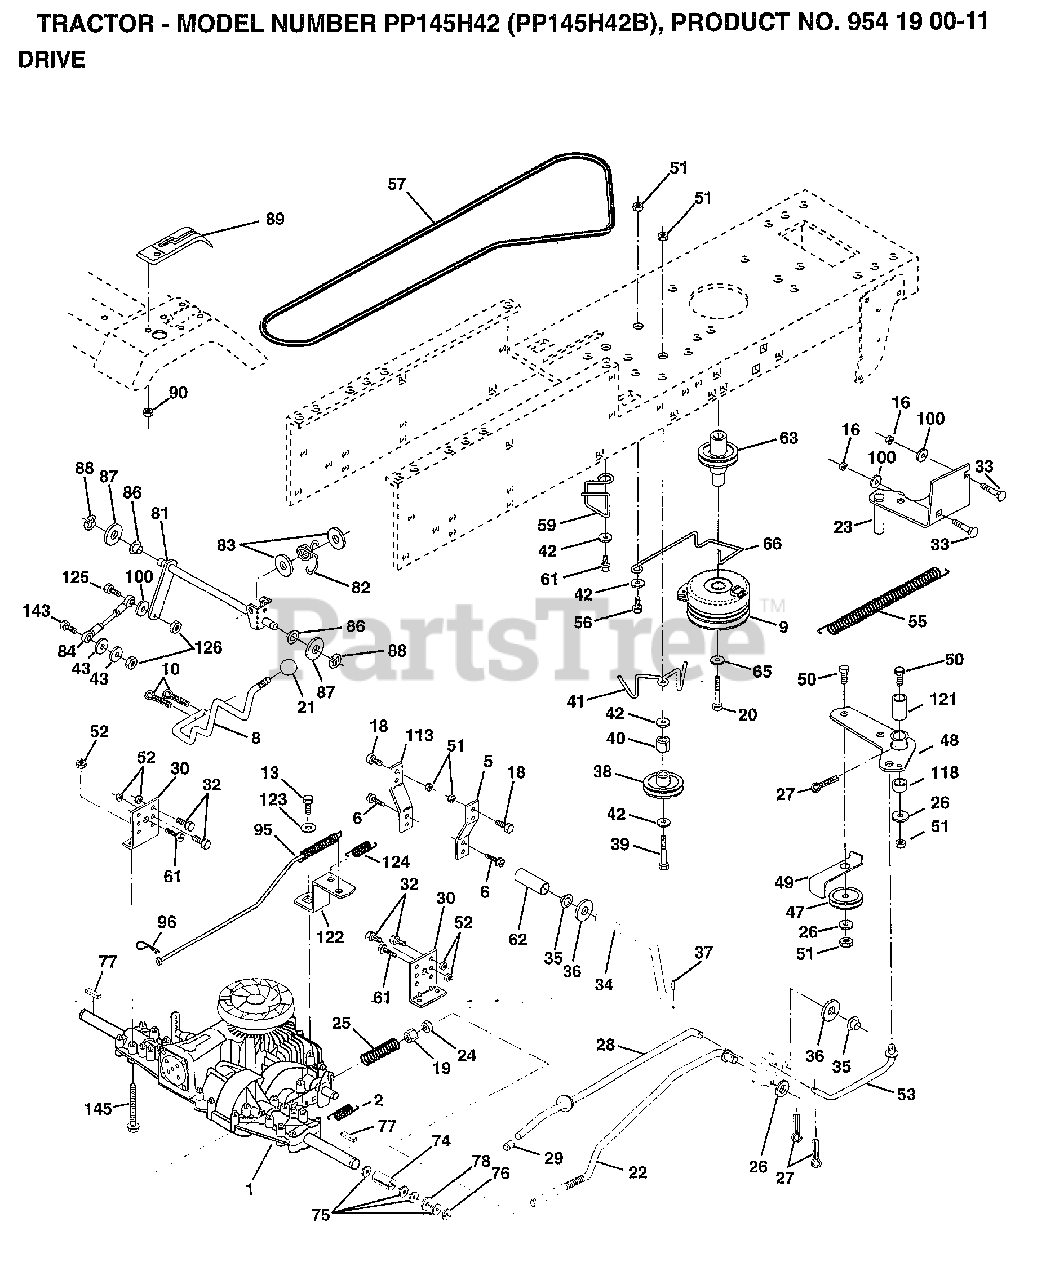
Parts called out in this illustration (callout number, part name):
2	SPRING.BRAKE.RETU
5	STRAP TORQUE
6	SCREW
8	ROD SHIFT FEND LT
9	CLUTCH.ELECT.EVX.
10	PIN COTTER 1/8
13	BOLT.1/4-28.W/PAT
16	NUT
18	BOLT
19	NUT
20	BOLT.7/16-20X4.25
21	KNOB.DUCKHEAD.1/2
22	BRAKE ROD
23	BRACKET.CLUT.MTG.
24	NUT
25	SPRING ROD LT
26	WASHER
27	COTTER PIN
28	ROD.BRAKE.PARK.LT
29	PLUNGER CAP T
30	TRANSAXLE MTG BKT
32	BOLT
33	BOLT
34	SHAFT ASM-PEDAL F
35	NYLON BEARING
36	WASHER LT
38	PULLEY.IDLER.FLAT
39	BOLT
40	SPACER T
42	WASHER
43	WASHER T
48	BELLCRANK ASM
49	RETAIN BELT
53	"LINK, CLUTCH T"
55	"SPRING, RETURN LT"
57	"V-BELT,GRD DRIVE"
59	KEEPER BELT CNTSP
61	SCREW
62	PEDAL COVER T
63	PULLEY.CLUTCH.EVX
65	LOCKWASHER
66	KEEPER-BELT
69	SCREW HEXWSH H-L
74	"SPACER AXLE,PVST"
75	WASHER
76	E-RING LT
77	SQUARE KEY
78	WASHER
81	SHAFT ASM CROSS
82	"SPRING,TORSION"
83	WASHER
84	ROD TIE
86	BUSHING
87	WASHER D
88	KLIP RING
95	ROAD ASM BYPASS
96	RETAINER M
100	WASHER M
113	"STRAP,TORQUE"
114	WASHER
118	SPACER-BELLCRANK
121	NYLINER-CLUTCHING
122	"PLATE-BYPASS,PVST"
123	WASHER
124	SPRING RETURN
143	BOLT
145	BOLT.HEX.FLGHD
